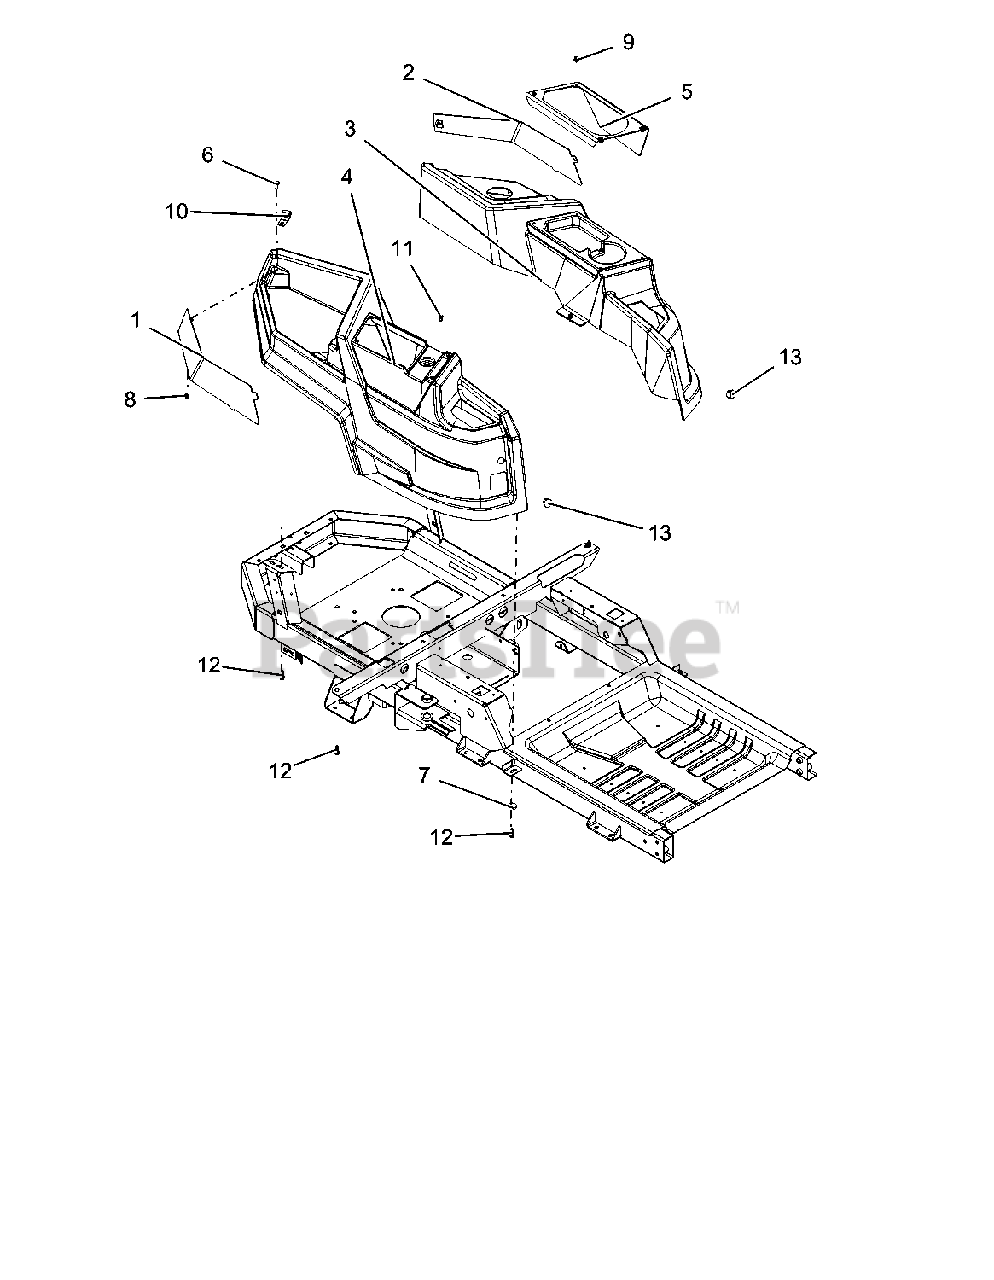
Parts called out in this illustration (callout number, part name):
1	WLDMT, PANEL BLOCKOFF-RH (RED)
2	WLDMT, PANEL BLOCK OFF-LH -RED
3	FENDER, LH -ZOOM
4	FENDER, RH -ZOOM
5	PANEL, CONTROL /CUP-LH
6	BLT-HEX .25-20X.63 GR5 BLKZC
7	WSHR-FL-STL .406X1.00X.188 YWZC
8	NUT, LK-TOP-FLG .25-20 YWZC
9	RVT-POP .195 PLASTIC
11	SCR-TAP .25-20X.50 HWH TR YWZ
12	SCR-HEX .312-14X.75 H/L
13	PLUG, HOLE .750-BLACK
